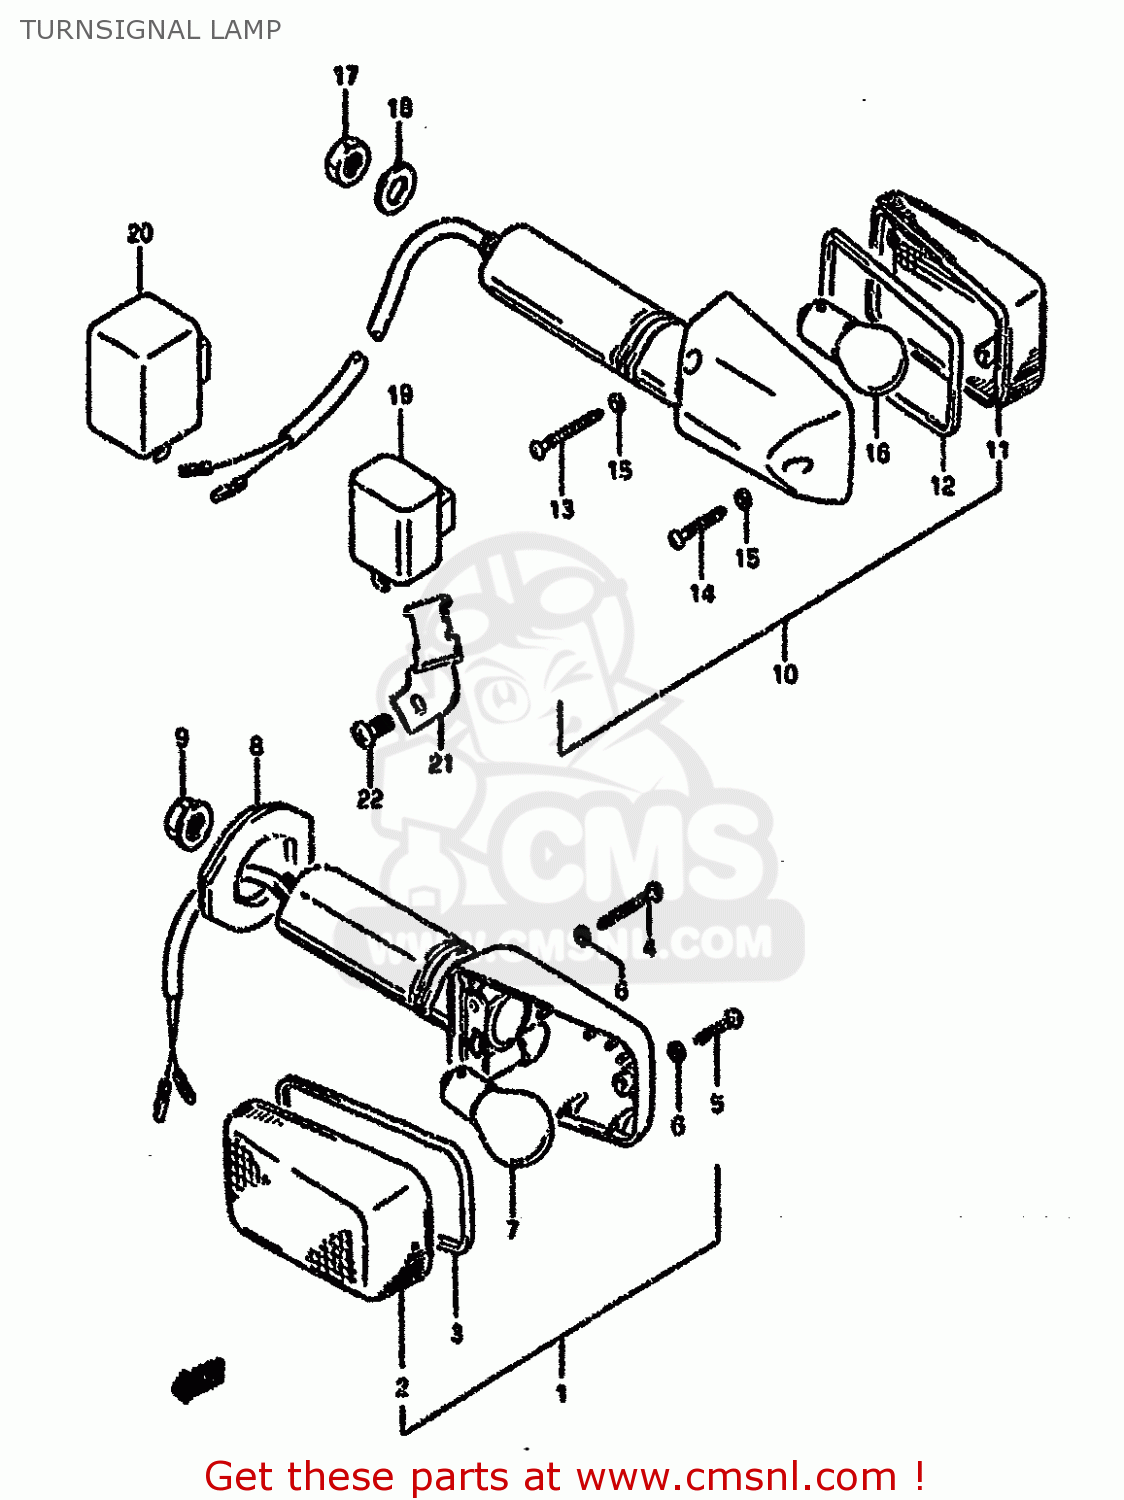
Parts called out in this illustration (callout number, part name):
1	LAMP ASSY,FR TURN SIGNAL
2	LENS
3	GASKET (NAS)
4	SCREW(3X30)
5	SCREW
6	GASKET (NAS)
7	BULB(12V21W)
8	GROMMET
9	NUT
10	LAMP ASSY,RR TURNSIGNAL
11	LENS
12	GASKET (NAS)
13	SCREW(3X30)
14	SCREW
15	GASKET (NAS)
16	BULB(12V21W)
17	NUT
18	WASHER 10MM
19	RELAY ASSY,TURNSIGNAL
20	RELAY ASSY,TUR
21	BRACKET,RELAY
22	SCREW
